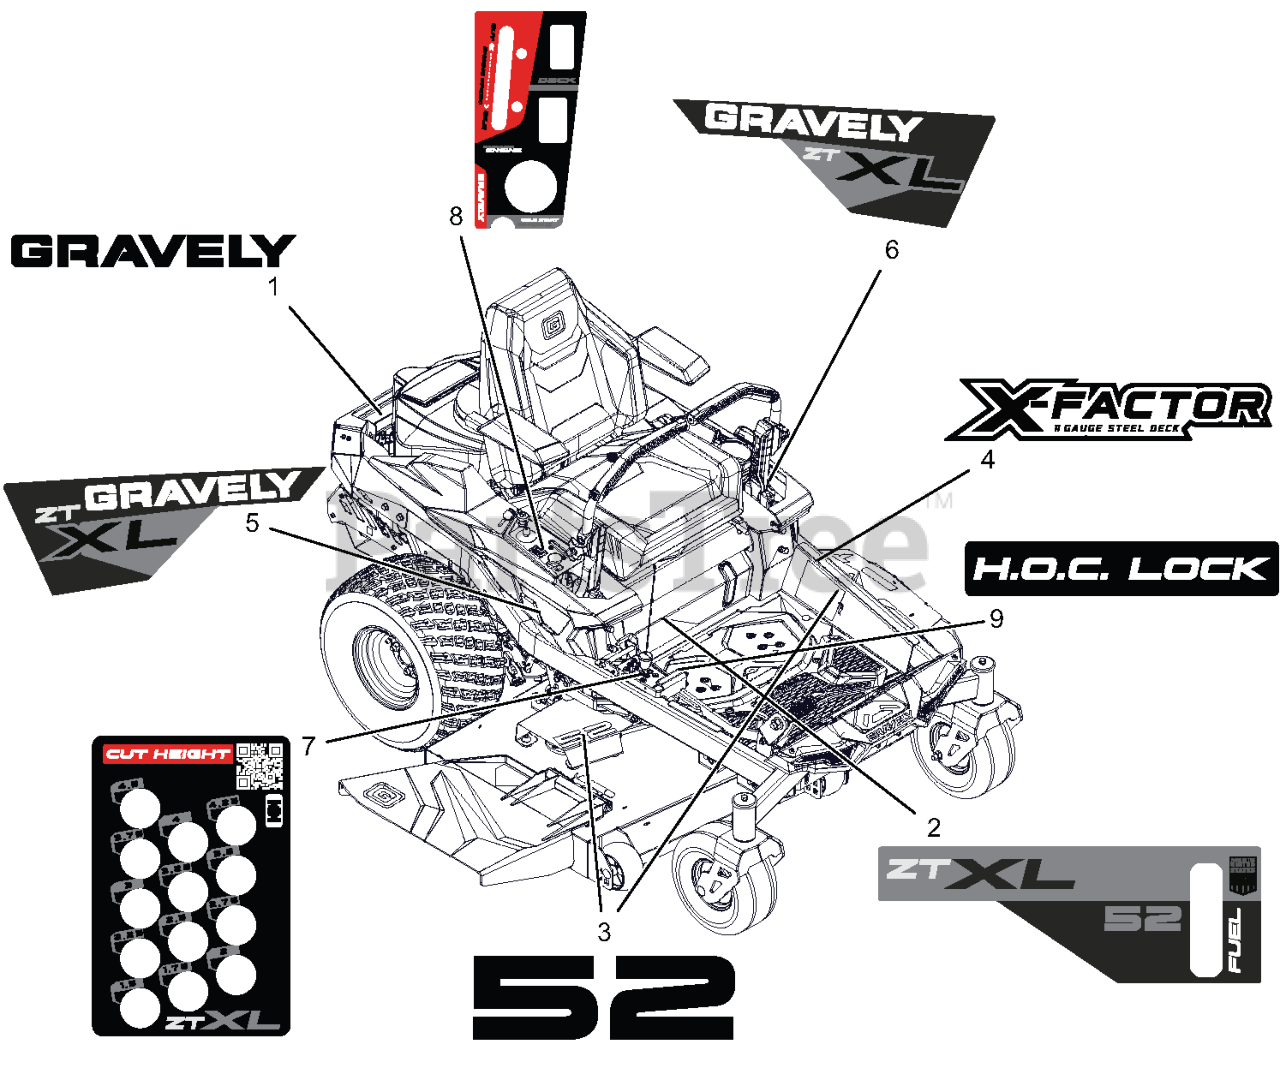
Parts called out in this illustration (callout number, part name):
1	DECAL- GRAVELY
2	DECAL- ZTXL 48-KICK PLATE
3	DECAL- DECK 48"
4	DECAL- DECK X-FACTOR
5	DECAL- ZT XL FENDER RH
6	DECAL- ZT XL FENDER LH
7	DECAL- HEIGHT OF CUT-XL
8	DECAL- CONTROL PANEL-GRAVELY
9	DECAL- HOC LOCK
